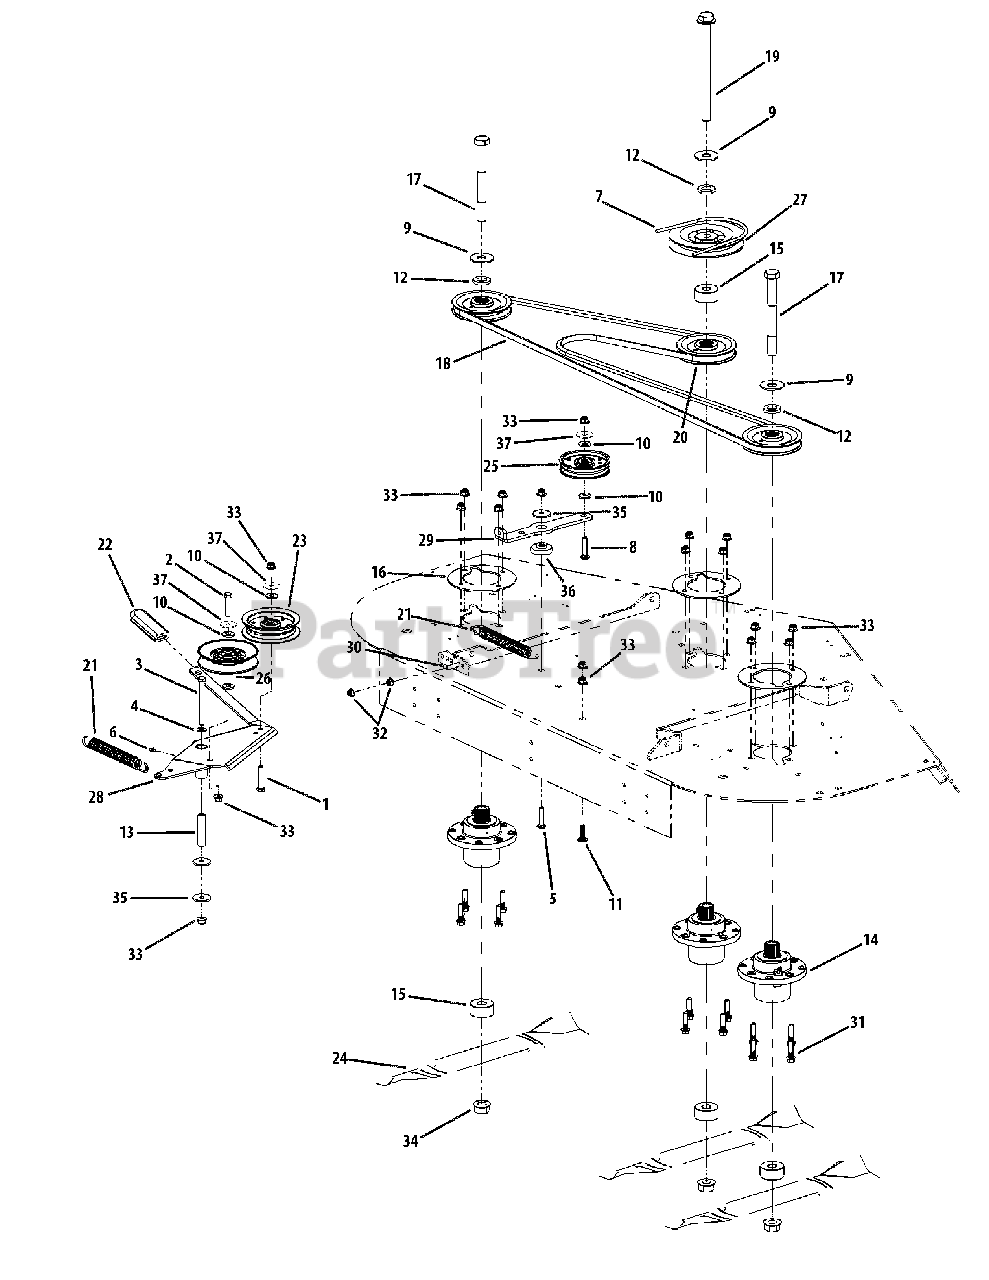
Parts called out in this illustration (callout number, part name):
1	Hex Cap Screw, 3/8-16 x 2.00
2	Hex Cap Screw, 3/8-16 x 1-3/4
3	Hex Cap Screw, 3/8-16 x 4.00
4	Washer, 3/8
5	Carriage Bolt, 3/8-16 x 1-1/2
6	Grease Fitting, 1/4-28 x 3/16
7	V-Belt, B-Section, BK90
8	Carriage Bolt, 3/8-16, 2.00
9	Flat Washer, .781 ID 2.00 OD, .105
10	Flat Washer, .406 ID, 1.0 OD, .105
11	Carriage Screw, 3/8-16 x 1.25
12	Spacer .812 ID x .268 LG
13	Spacer, .39 ID x .625 OD x 2.75
14	Aluminum Spindle Assembly
15	Spacer, .760 ID x 2.00 OD x 1.1
16	Aluminum Spindle Support Plate
17	Hex Cap Screw, 3/4-16, 7.00
18	V-Belt, A Section x 122.3
19	Hex Cap Screw, 3/4-16, 9.00
20	V-Pulley, 5.00 OD
21	Extension Spring, .94 x OD x 7.57
22	Grip, 1.0 x 3.2 x .25
23	Idler Pulley, 4.06 OD
24	Hi-Lift Blade, 21.0, 0.756 ID
24	Bahia Blade
25	Flat Pulley with Flanges
26	Idler Pulley, 5.06 OD
27	V-Pulley, 6.38 OD x .760 ID
28	Idler Arm Assembly
28	Bearing
30	Carriage Bolt, 5/16-18 x 1.50
31	Bolt, 3/8-16 x 1.5
32	Nut, 5/16-18, Nylon Flange Lock
33	Nut, 3/8-16, Nylon Flange Lock
34	Flange Hex Nut, 3/4-16
35	Washer, .390 x 1.500 x .134
36	Shoulder Screw, .854 x .280
37	Washer, .406 x 1.92 x .060
